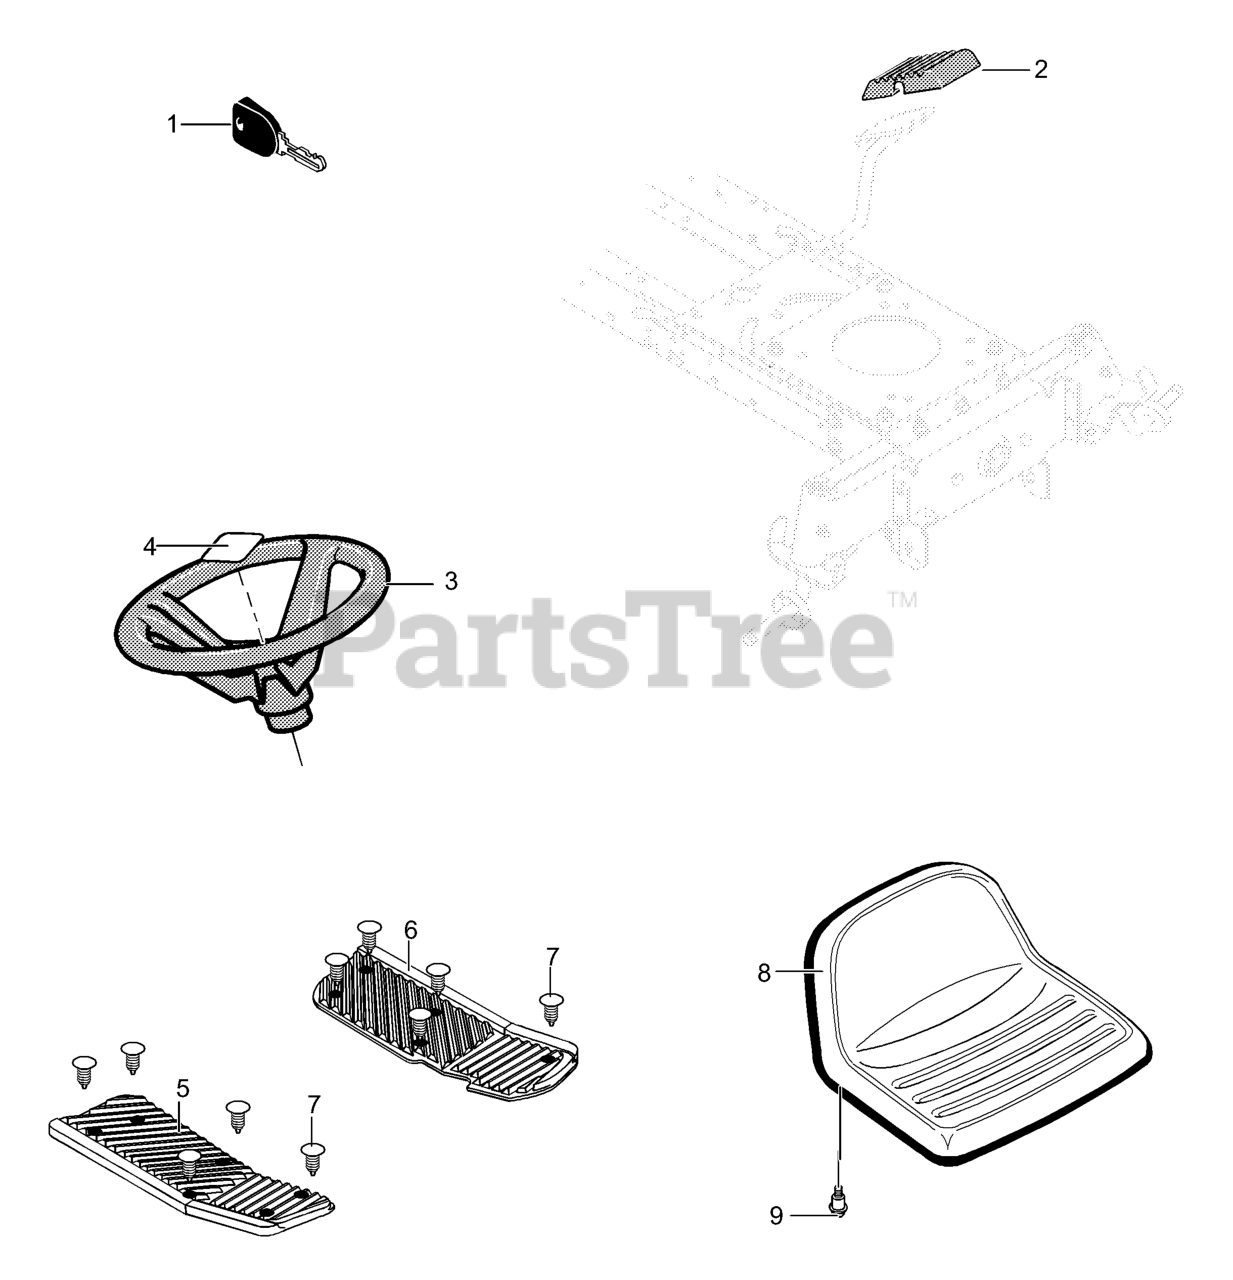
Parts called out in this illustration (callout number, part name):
1	IGNITION KEY
2	PAD, BRAKE/CLUTCH
3	STEERING WHEEL
4	INSERT, 4-SPOKE
5	PAD, RIGHT FOOTREST
6	PAD, LEFT FOOTREST
7	FASTENER, RATCHET
